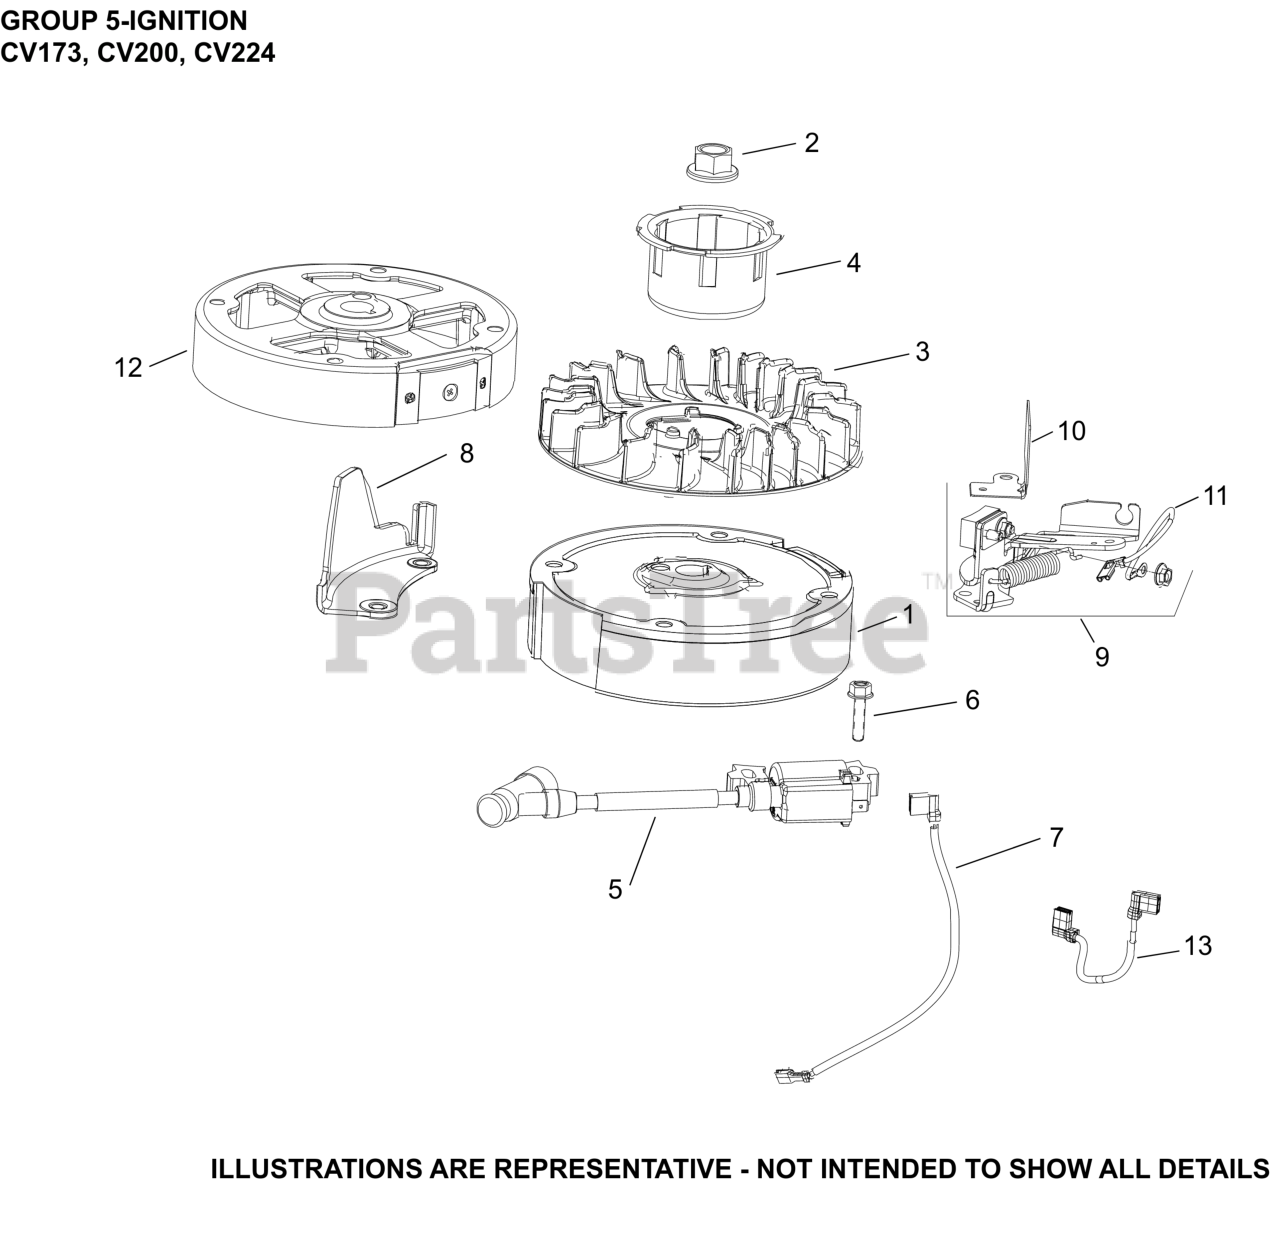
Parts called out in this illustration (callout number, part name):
2	NUT, FLYWHEEL (W/SERRATIONS)
3	FAN, FLYWHEEL
4	CUP, STARTER DRIVE
5	MODULE IGN (#1458416S)
6	SCREW, M6 X 25-(#25086436S)
8	GUARD, FINGER
12	FLYWHEEL ASSEMBLY
